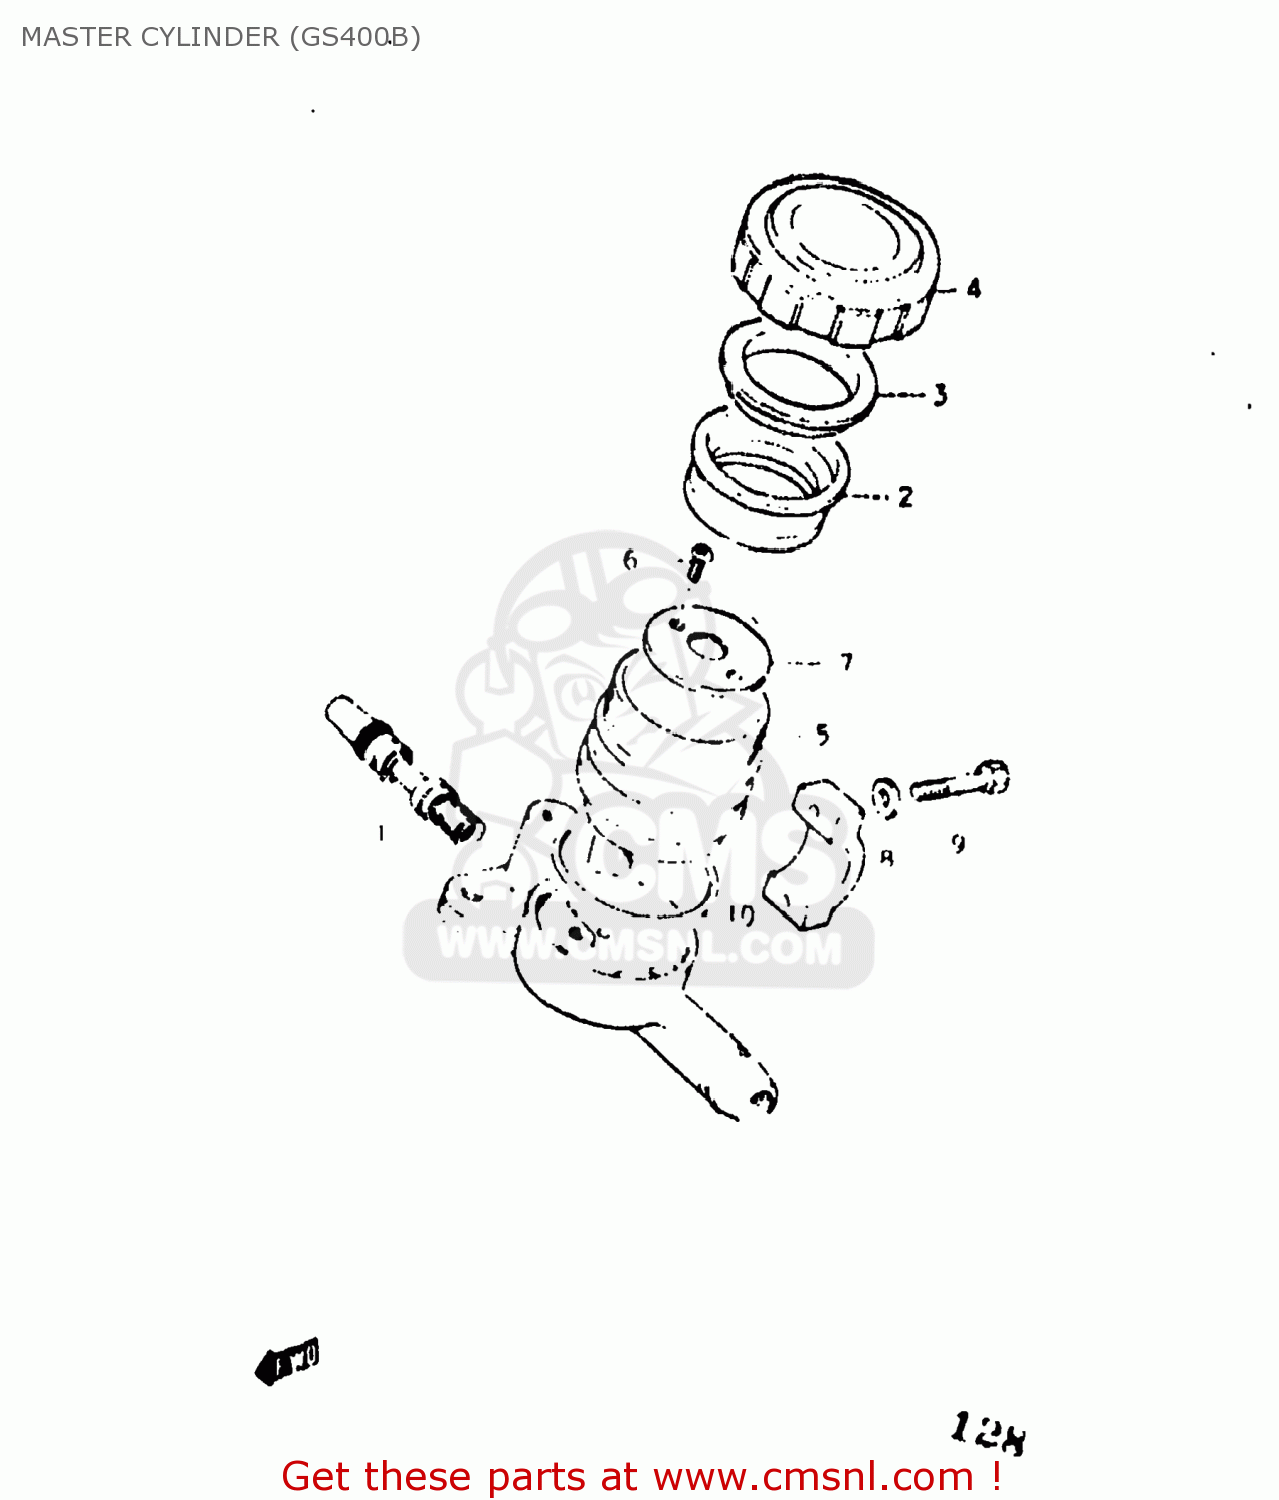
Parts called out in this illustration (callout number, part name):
1	PISTON & CUP SET
2	DIAPHRAGM
3	PLATE
4	CAP,MASTER CYLINDER,REAR
5	RESERVOIR,MASTER CYLINDER
6	SCREW,MASTER CYLINDER
7	BOLT
8	WASHER
9	O RING
